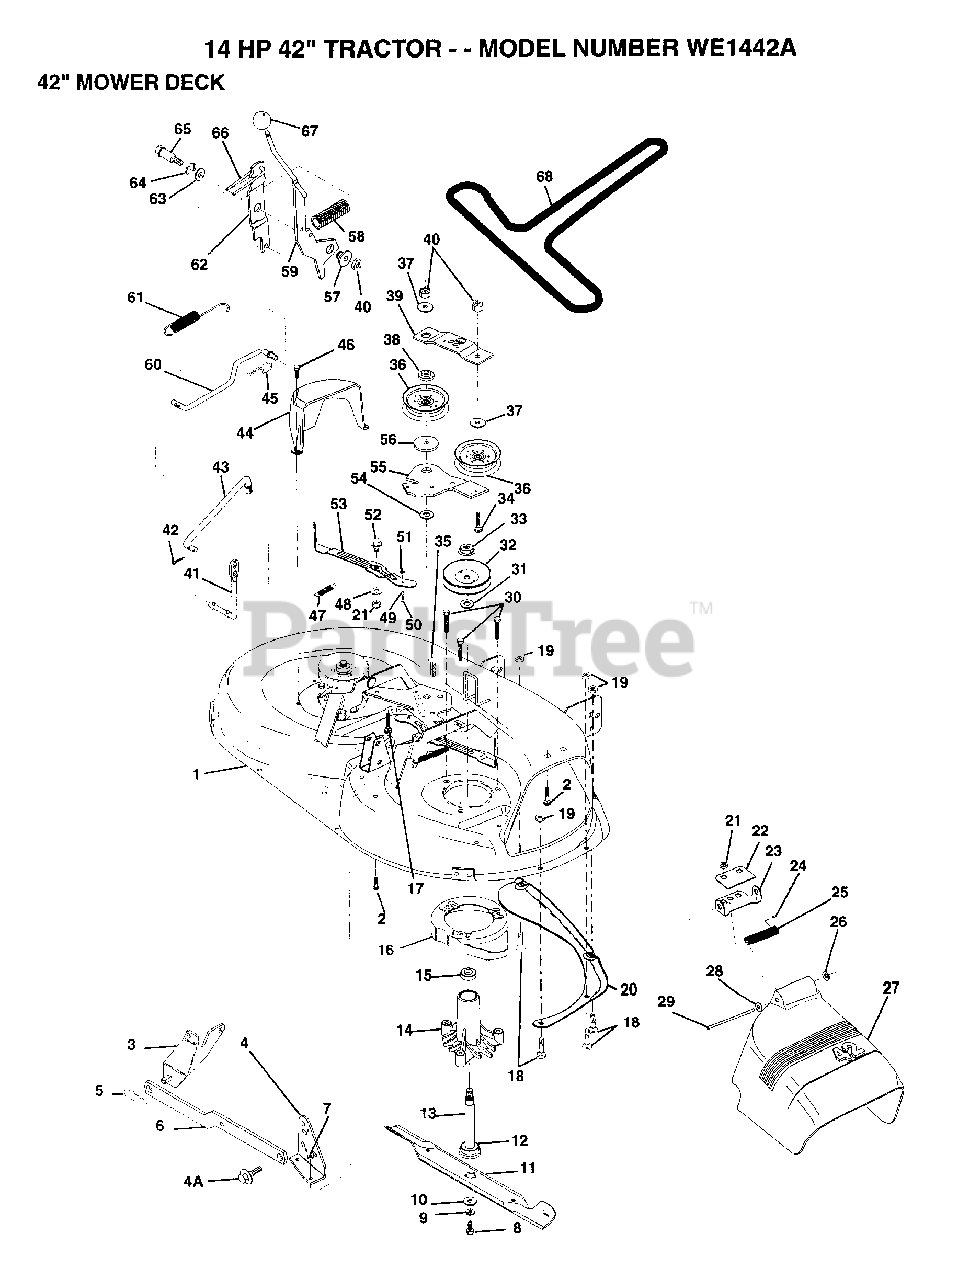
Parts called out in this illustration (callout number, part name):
2	BOLT
3	BRKT ASM SWAY BAR
4	BRKT DECK SW BAR
4A	BOLT SHD 5/16-18
7	NUT
8	BLADE BOLT
10	WASHER BLADE
11	"BLADE.42"" HIPERF"
12	BEARING.BALL
14	HSG ASM MANDREL
15	BEARING
17	BOLT CARRIAGE
18	BOLT
19	NUT
22	STIFFENER BRKT
23	DEFLECTOR BRKT
24	CAP-SLEEVE LT
25	SPRING TORSION
26	NUT PUSH M
27	DEFLECTOR.SHIELD
28	WASHER
29	HINGE ROD
31	WASHER
34	BOLT
35	XMAS TREE FASTNER
36	FLAT IDLER PULLEY
37	WASHER GT
38	RETAINER SPACER
39	IDLER ARM STIFF
41	PIVOT ROD
43	CLUTCH ROD SECOND
45	RETAINER M
46	SCREW.1/4-20X5/8
47	SPRING EXTENSION
48	HARD SMALL WASHER
50	SHOULDER BOLT
51	LOCKNUT
53	BRAKE PAD ARM ASM
54	HARDENED WASHER
55	IDLER ARM
56	SPACER RETAINER
57	BUSHING
59	CLUTCH ARM PRI AS
60	"ROD, CLUTCH PRIM"
61	RETURN SPRING
62	CLUTCH ARM SECOND
63	WASHER
64	RING
65	SHOULDER BOLT
66	SPRING KEEPER
67	KNOB T(3/8 HOLE)
68	BELT-V.92.4.MWR
